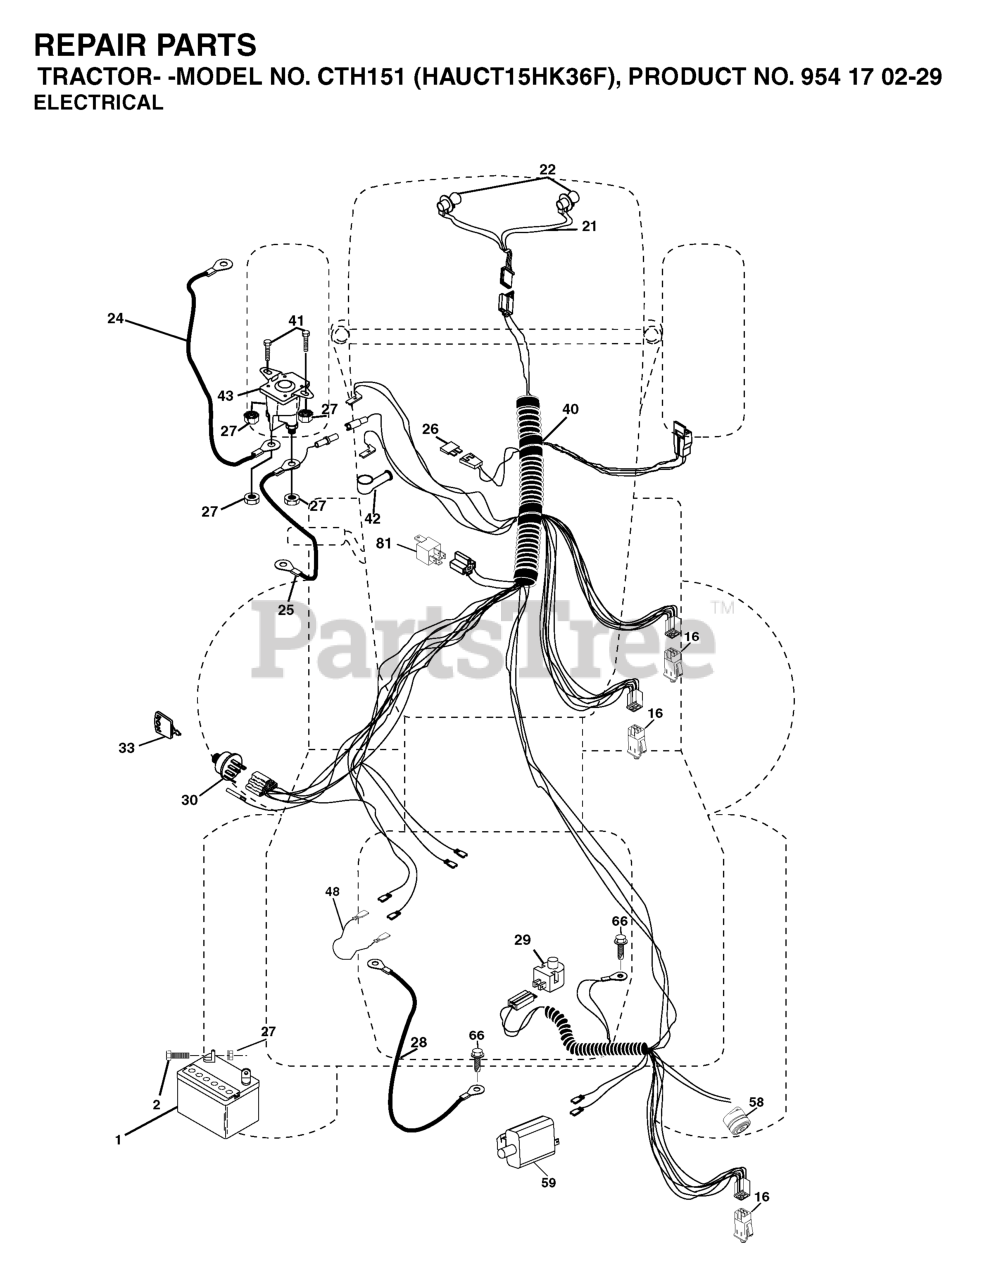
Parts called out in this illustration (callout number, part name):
1	BATTERY 12V .35 AMP
2	BOLT.HEX.1/4.X.3/4.DICHROMATE
16	SWITCH INTERLOOK PUSH-IN
21	HARNESS.W/LIGHT SOCKET
24	BATTERY CABLE GT
25	CABLE BATTERY
26	FUSE 20AMP
27	NUT
28	CABLE GROUND
29	RP.SWITCH.PLUNGER.NC.GRAY
30	IGNITION SWITCH
33	KEY MLD GEN DELTA
41	BOLT
42	TERMINAL COVER
43	SOLENOID
48	ADAPTER.AMMETER
58	BUZZER
59	.WITCH.FULL BAGGER.INDICATOR
81	RELAY.ASSY.T
